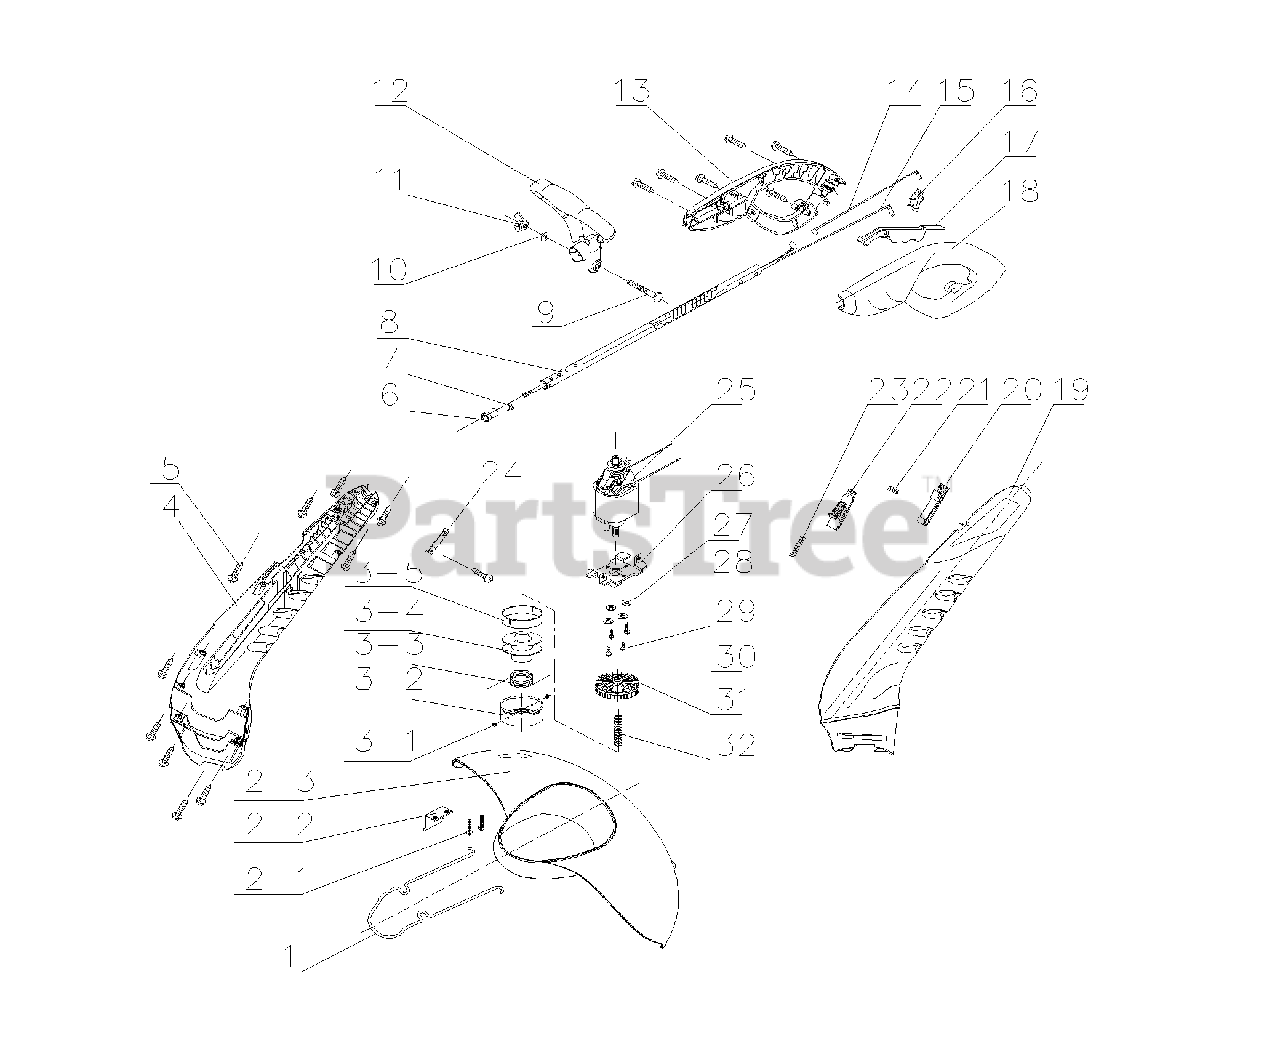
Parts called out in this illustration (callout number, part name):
2	GUARD ASS'Y
3	SPOOL CARRIER ASS'Y
4	HOUSING (R)
7	SNAP BUTTON
12	CENTRAL HANDGRIP
13	UPPER HANDGRIP (R)
18	UPPER HANDGRIP (L)
19	HOUSING (L)
25	MOTOR 120V
26	MOTOR PLATE
31	CUTTER ASS'Y
